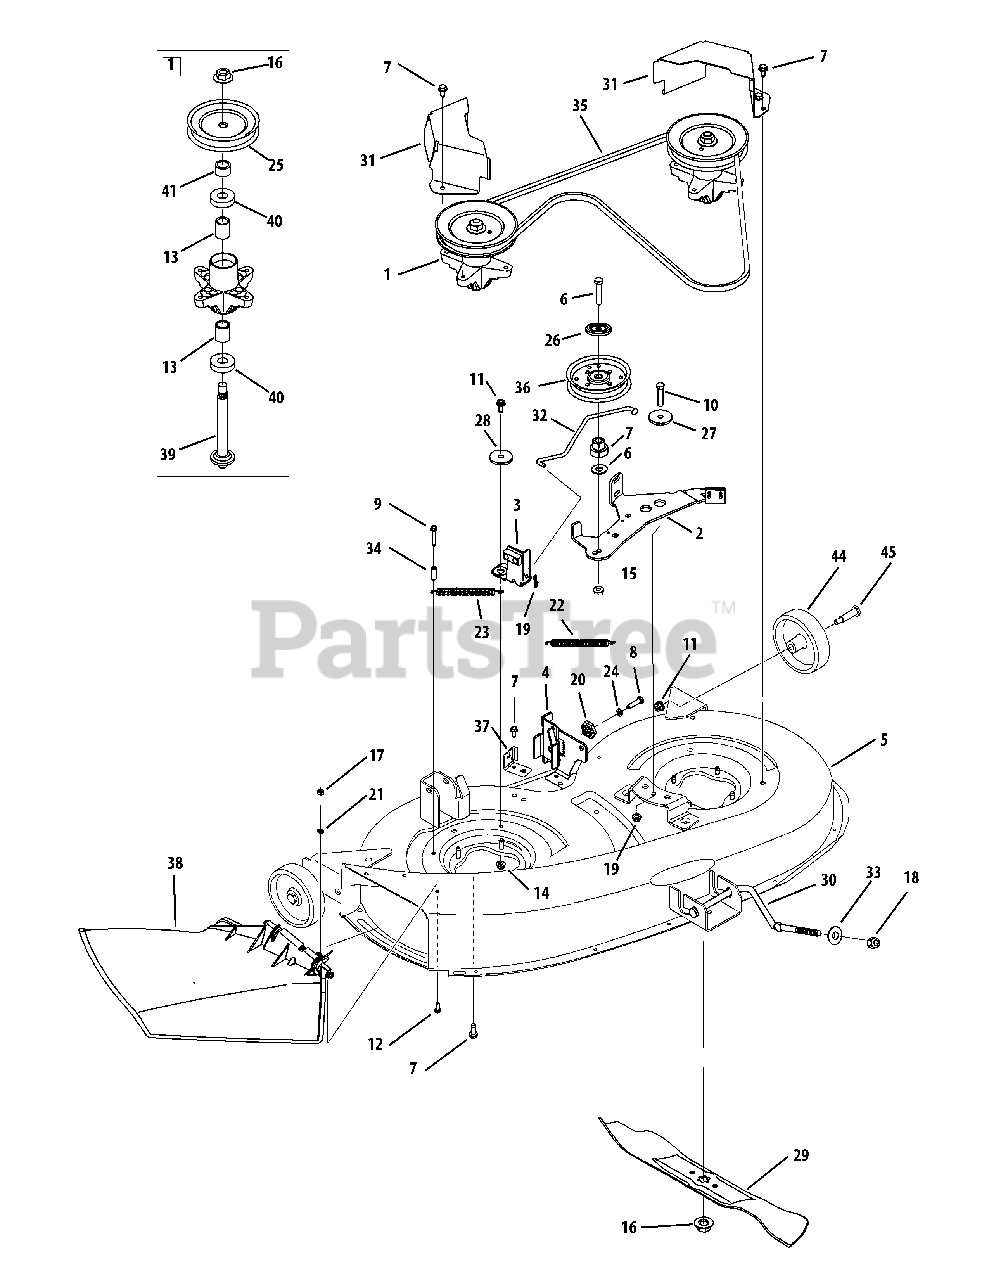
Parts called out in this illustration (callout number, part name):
1	Pulley Spindle Ass’y 5.75 dia.
2	Deck Brake Assembly
3	Deck Brake Asembly
4	Deck Hanger Brkt. Ass’y
5	Deck Shell, 38" (w/ wheel brackets)
6	Hex Screw 3/8-16 x 1.75
7	Hex Wash TT Scr 5/16-18 x .75
8	Hex Wash Tap Scr 5/16-18 x 1.25
9	Hex Wash HD Bolt 1/4-20 x 1.50" Lg.
10	Hex Bolt 3/8-16 x 1.25
11	Hex Bolt 5/16-18 x .75" Lg. Gr. 5
12	Hex Bolt 1/4-20 x .62 Gr. 5
13	Flexloc Nut 1/2-13
14	Hex Flange Locknut 5/16-18 Gr. F, Nylon
15	Hex Flange Locknut 3/8-16 Gr. F Nylon
16	Hex Flange Locknut 5/8-18
17	Hex L-Flanged Nut 1/4-20 Gr. F Nylon
18	Hex Nylok Nut 1/2-13
19	Bow Cotter Pin
20	Deck Adjustment Gear
21	Bolt Retainer 1/4" x .50" OD
22	Extension Spring .75 dia. x 6.37 Lg.
23	Extension Spring .50 dia x 6.37
24	L-Wash 5/16 ID
26	Pulley Cap
27	Shoulder Spacer .8540 x .200
28	Shoulder Spacer
29	3 in 1 Blade 19.38" Lg.
30	Deck Rod, Front Adjustable
31	Belt Cover 5.66 dia.
32	Brake Control Rod
33	Deck Lift Pivot Cup
34	Spacer .260 x .375 x 1.030 Lg.
35	V-Belt
36	Idler Poulie w/Flange 4.25 Dia
37	Deck Engage Cable Bracket
38	Side Discharge Chute Assembly
39	Spindle Shaft 5.5
40	Ball Bearing .787 ID x 1.85 OD x .551
41	Spacer, .820 x 1.150 x .480
42	Spacer .80 x 1.10 x 1.322
43	Deck Pul ley
44	Deck Wheel
45	Shoulder Bolt .498 Dia x 1.53 x 3/8-16
